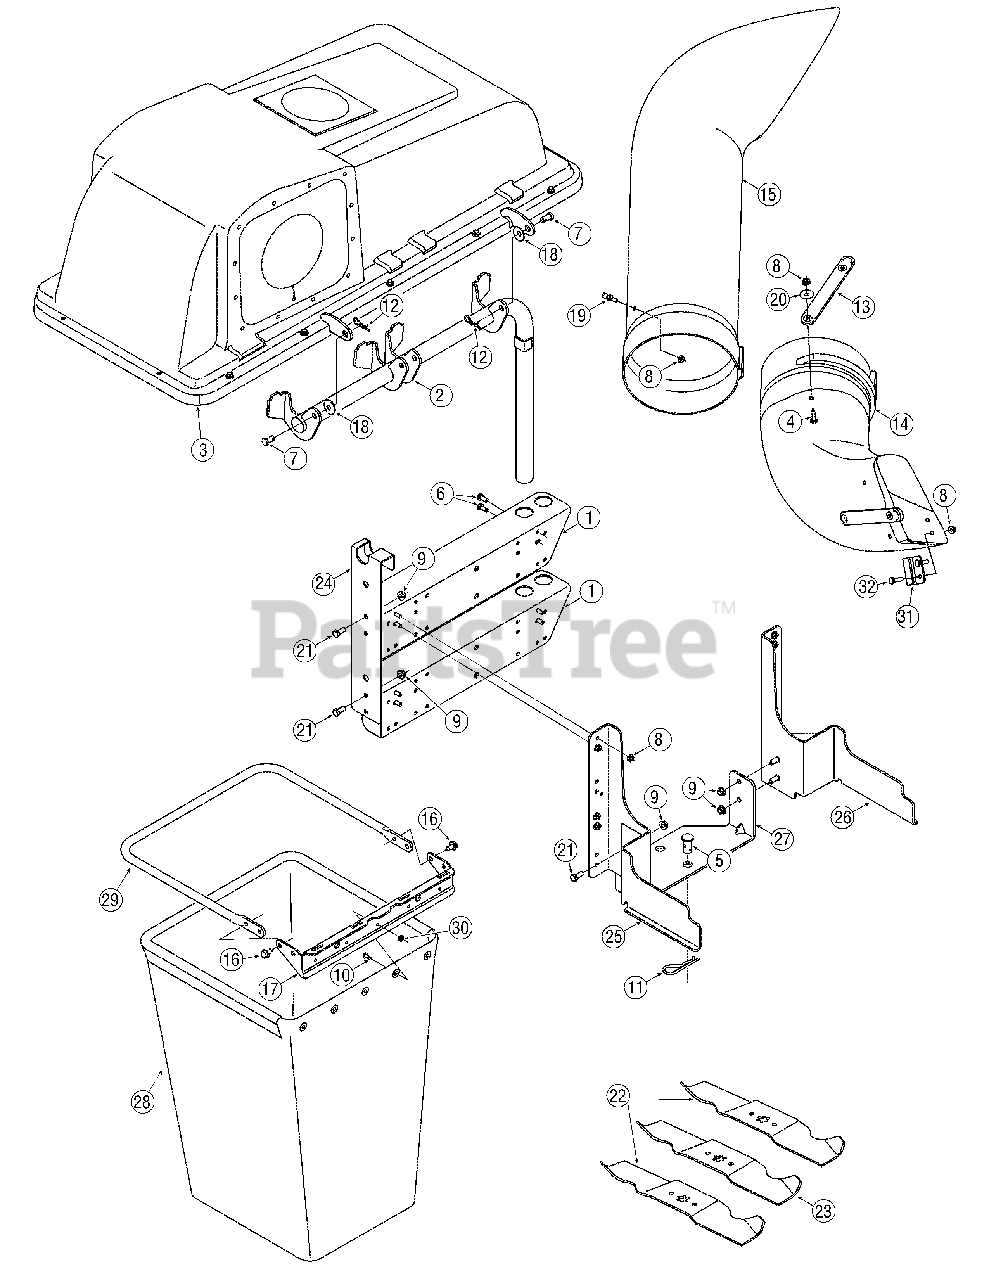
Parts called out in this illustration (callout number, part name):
3	Grass catcher Cover Assembly
4	SCREW 1/4-20 X1.00 GR5
5	Clevis Pin
6	SCREW 1/4-20 x .620 GR5
7	Clevis Pin
8	Flange Lock Nut, 1/4-20
9	Flange Lock Nut, 5/16-18
10	Machine Screw, #10-24 x .5
11	Hairpin Clip
12	Click Pin
13	Chute Strap - 46" Deck
14	Discharge Chute - 46" Deck
15	Catcher Tube
16	Self-Tapping Screw 5/16-18
18	Bell Washer
19	Grass catcher Pin
20	Flat Washer
21	SCREW 5/16-18 x .75 GR5
22	Blade 16.28" Lg. (2) - 46" Deck
23	Blade 14.88" Lg. (1) - 46" Deck
28	Catcher Bag
30	Hex Sems Nut, #10-24
